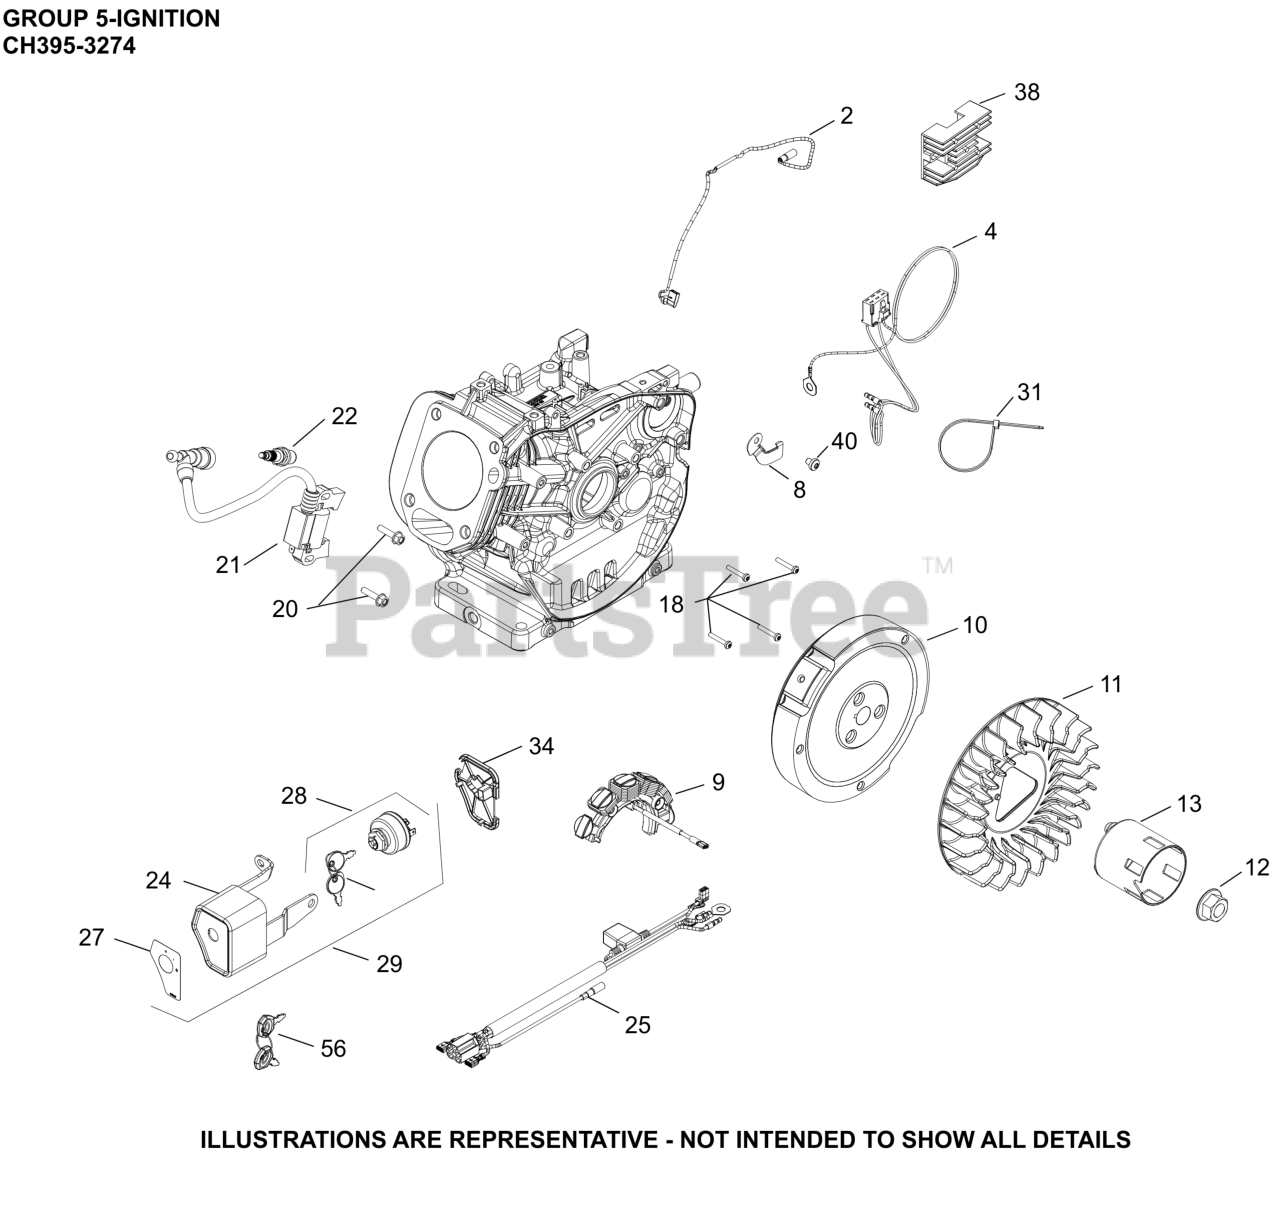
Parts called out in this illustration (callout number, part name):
2	LEAD, GROUND TO KILL
4	HARNESS, REGULATOR WIRING ASSY
8	BRACKET, STATOR WIRE
9	STATOR ASSEMBLY, 10A
10	FLYWHEEL ASSY ELECTRIC START (CH395)
11	FAN, FLYWHEEL
12	NUT, FLYWHEEL
13	CUP, STARTER DRIVE
18	SCREW, STATOR MOUNTING
20	SCREW, M6 X 25-(#25086436S)
21	MODULE, SPARK PLUG ASSY
22	SPARK PLUG
24	KIT, KEYBOX HOUSING ASSEMBLY
25	HARNESS, WIRING ASSEMBLY (10 AMP)
27	LABEL, KEY BOX
28	SWITCH, KEY ASSEMBLY
29	KIT, KEY BOX ASSEMBLY
34	COVER, KEY BOX
38	REGULATOR, 10 AMP
40	SCREW, COIL BRACKET
56	KIT, KEY PLASTIC HANDLE (2 PC)
